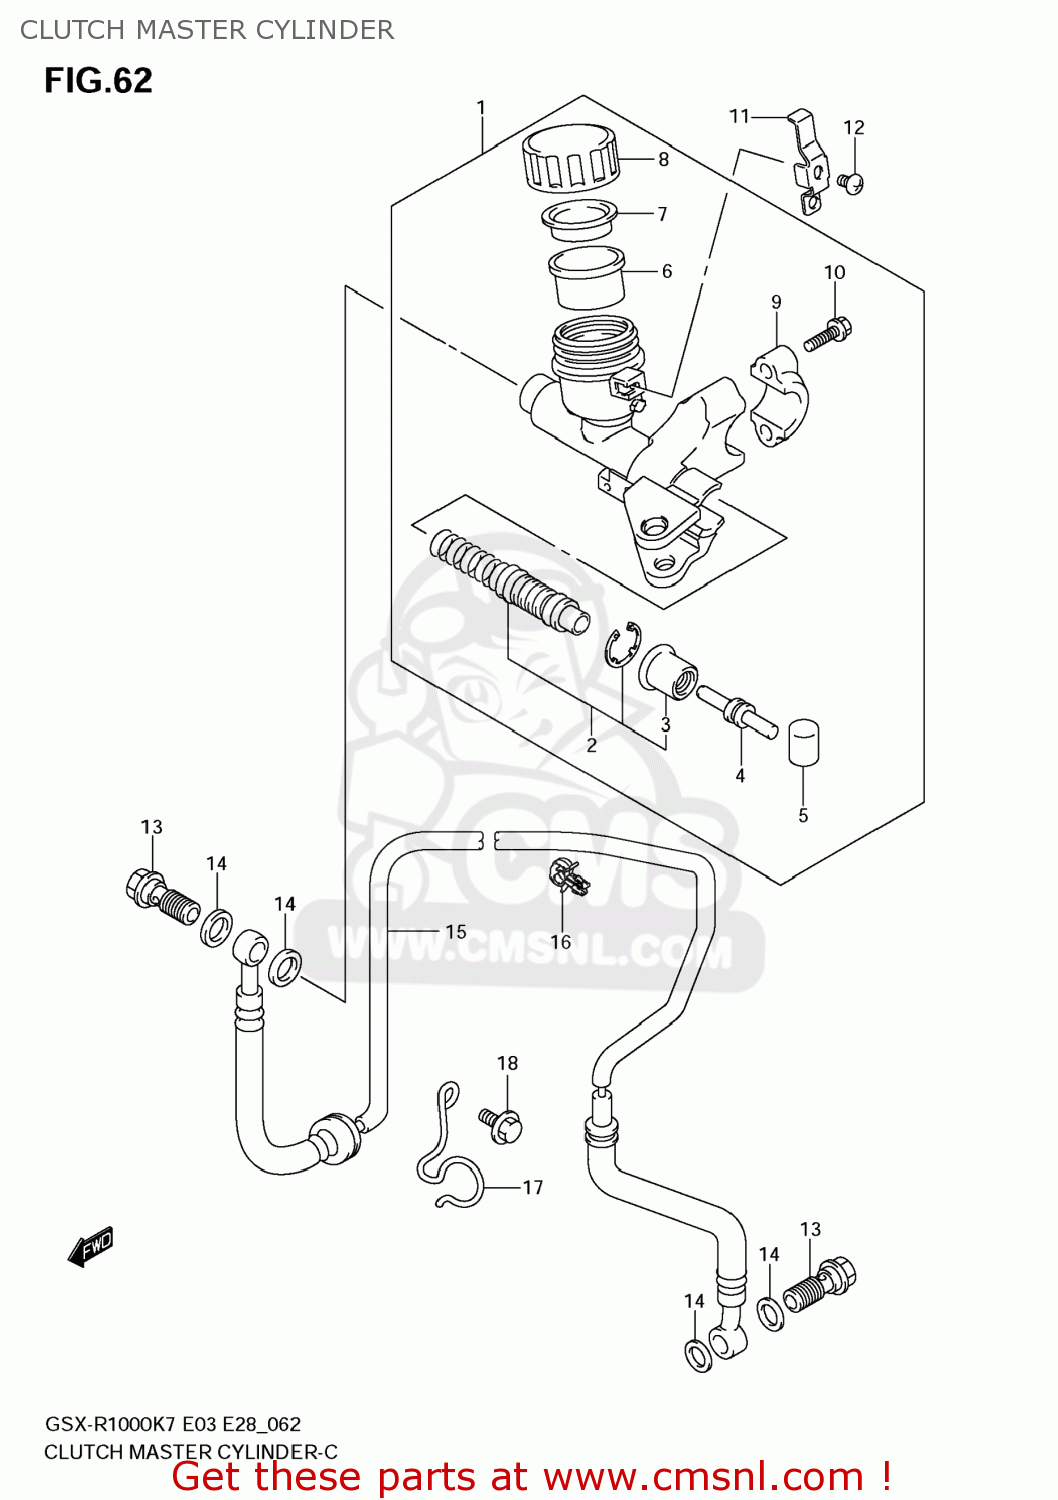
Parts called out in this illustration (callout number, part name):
1	CYLINDER ASSY,CLUTCH MASTER
2	PISTON & CUP SET
3	BOOT
4	PUSH ROD
5	BUSH
6	DIAPHRAGM
7	PLATE
8	CAP
9	HOLDER
10	BOLT(6X22)
11	PLATE,RESERVOIR TANK CAP
12	SCREW
13	BOLT UNION
14	WASHER(10X15X1.5)
15	HOSE,CLUTCH
16	CLAMP
17	CLAMP,CLUTCH HOSE NO.1
18	BOLT
